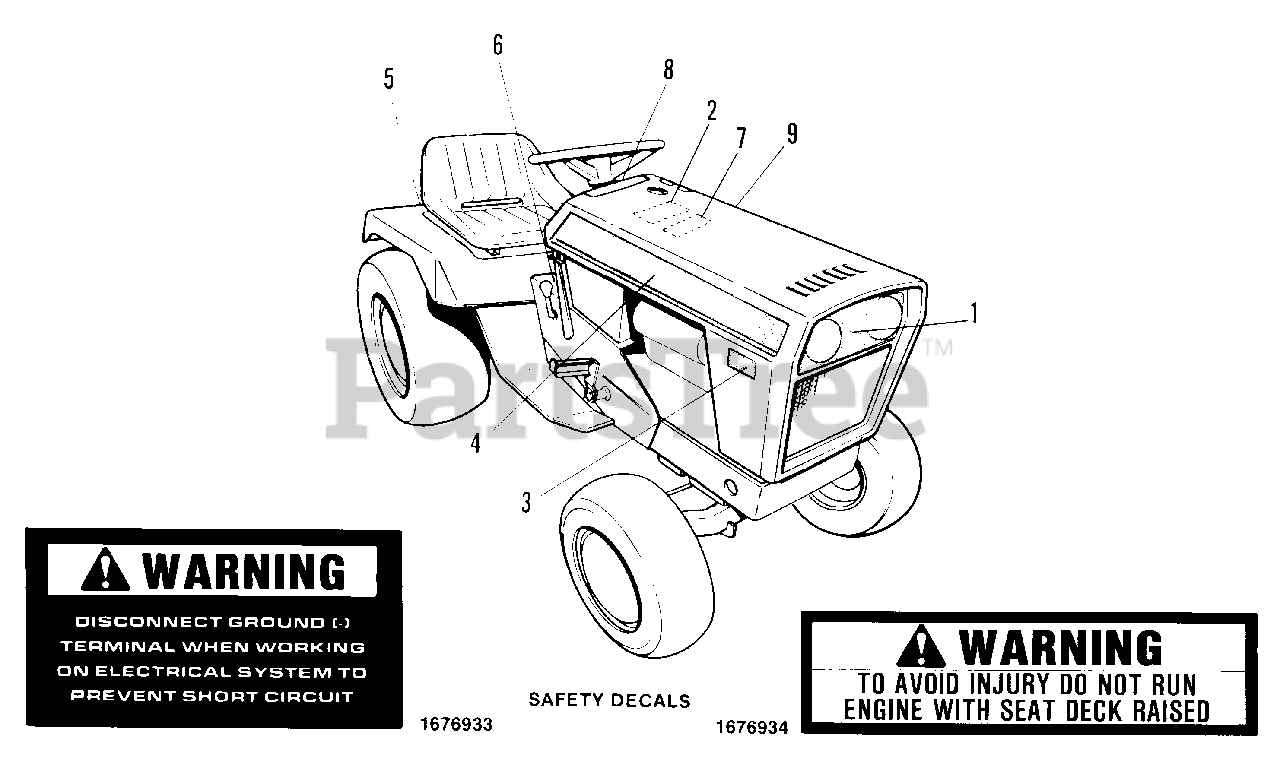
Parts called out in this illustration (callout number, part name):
1	DECAL, Grille
2	DECAL, Drive Belts & Mower Blades
3	DECAL, Model 17GTH-L
4	DECAL, Hood Stripe, RH
5	DECAL, Simplicity
6	DECAL, Console, Hydro
7	DECAL, Touch-Up Paint
8	DECAL, Dash, Hydro
9	DECAL, Hood Stripe, LH
9	DECAL, Battery
9	FILM, Lift Lever, (on handle)
9	DECAL, Adjustment, Mower Belt
9	DECAL, Caution
9	DECAL, Warning, (under seat deck)
